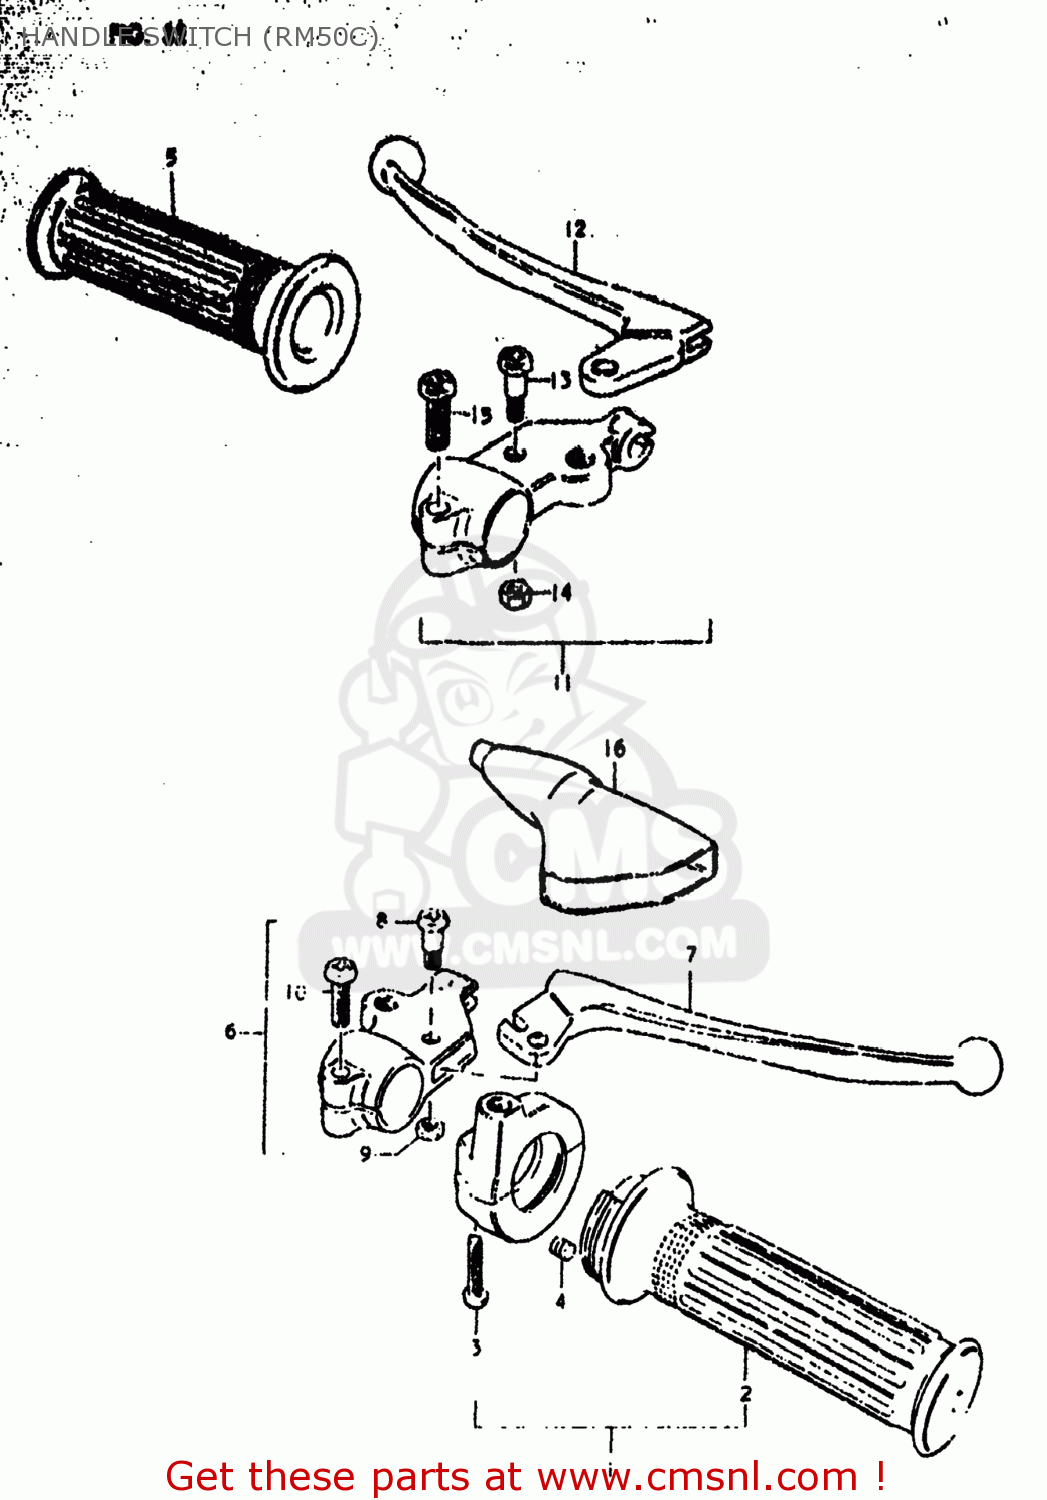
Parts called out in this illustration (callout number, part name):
1	CASE ASSEMBLY,THROTTLE
2	GRIP,THROTTLE
3	SCREW
4	PIECE,THROTTLE END
5	GRIP,L
6	LEVER ASSEMBLY,BRAKE
7	LEVER,BRAKE
8	BOLT,LEVER
9	NUT,LEVER BOLT
10	SCREW
11	LEVER ASSEMBLY
12	LEVER,CLUTCH
13	BOLT,LEVER
14	NUT
15	SCREW
16	COVER,CLUTCH LEVER
